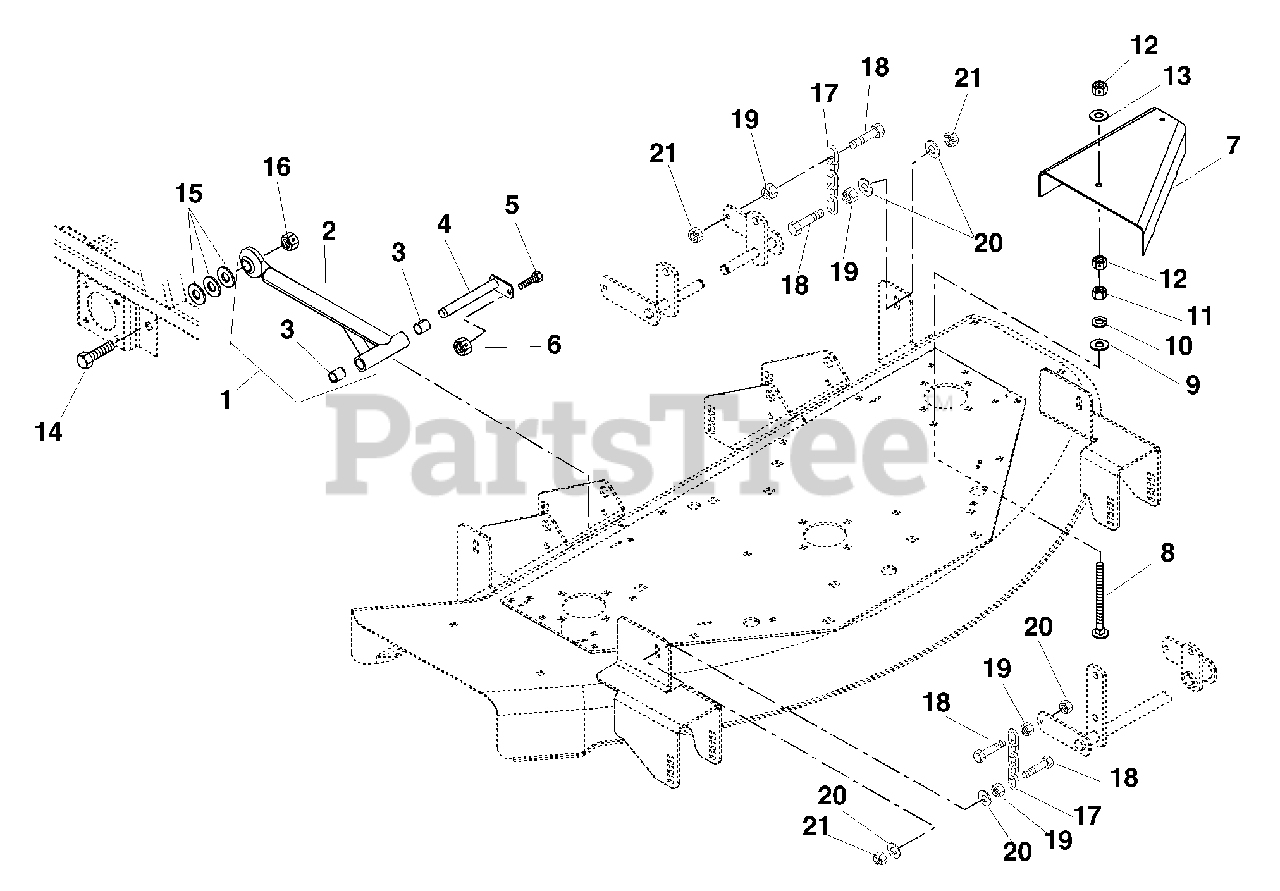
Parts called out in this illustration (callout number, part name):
1	Assembly, Mower Mounting Arm
2	Weldment-Mower Mounting Arm
3	Bearing .75 x .875 x 1.00
4	Weldment, Mower Mounting Pin
5	Bolt-Hex .38-16 x .75 Grade 5
6	Nut-Locking-Center .38-16
7	Guard, Pulley Right Hand
7	Guard, Pulley Left Hand
8	Bolt-Round Head Square Neck .31-18 x 3.50
9	Washer-Flat-Steel .344 x .688 x .065
10	Washer-Locking .31 x .078
11	Nut-Hex .31-18
12	Nut-Locking-Center .31-18
13	Washer-Flat-Steel .438 x 1.00 x.083
14	Bolt-Hex .875-9 x 2.75 Grade 5
15	Washer-Flat-Steel .875 x 1.500 x .1196
16	Nut-Locking-Center .875-9
17	Chain, Link
18	Bolt-Hex .38-16 x 1.50 Grade 5
19	Nut-Hex .38-16
20	Washer-Flat-Steel .406 x .812 x .065
21	Nut-Locking-Center .38-16
